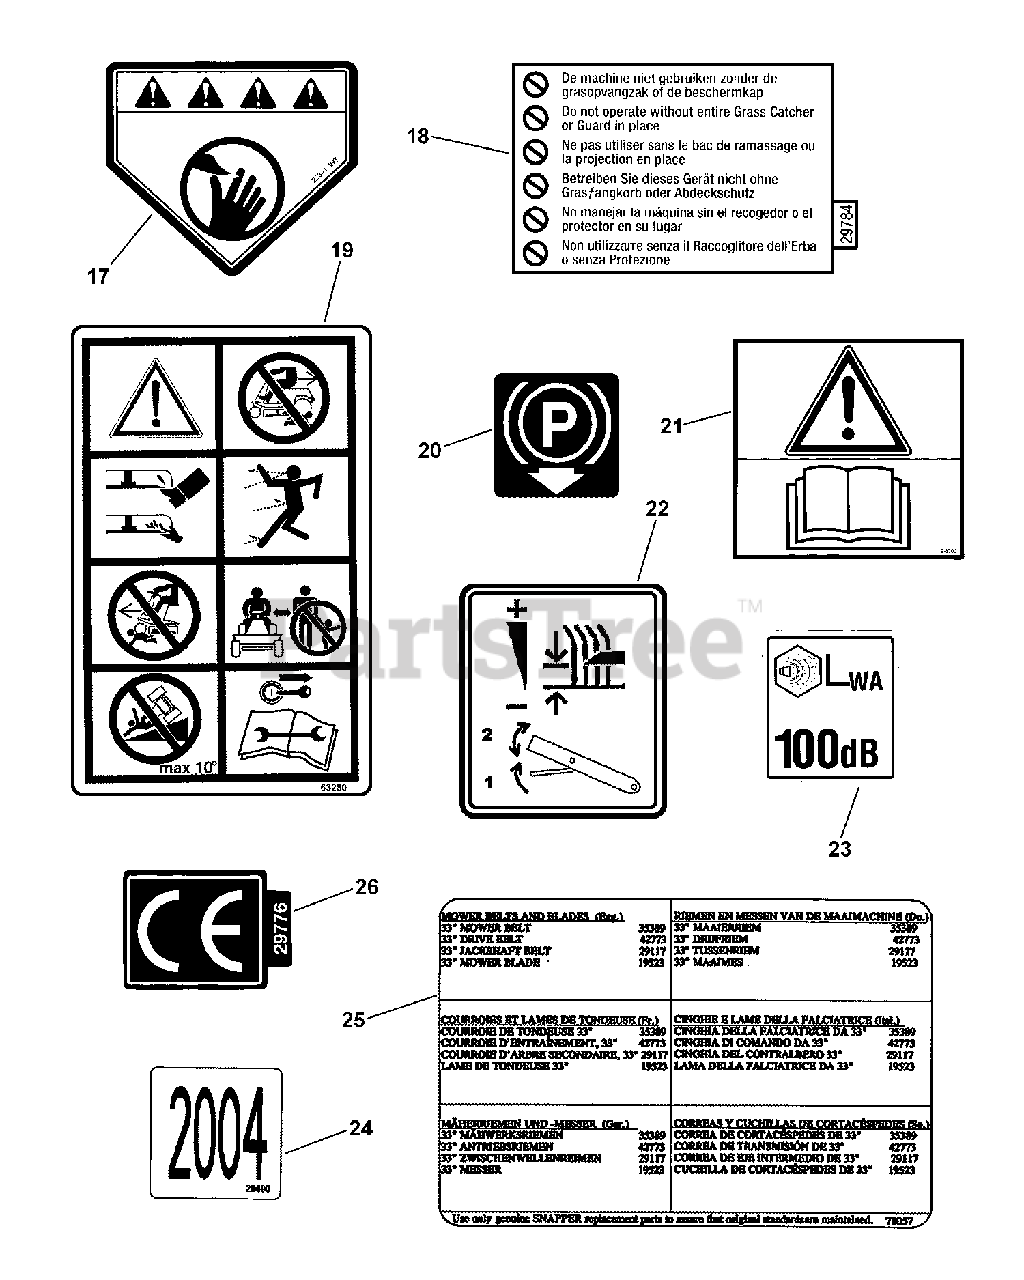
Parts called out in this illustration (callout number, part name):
17	DECAL, Warning, International Symbol
18	DECAL, Deck Chute, International Warning
19	DECAL, Safety Symbols
20	DECAL, Park Brake (Euro)
21	DECAL, Chute/Read Manual (Euro)
22	DECAL, Deck Adjust
23	DECAL, Sound 100
24	DECAL, 2004 Year of Manufacture
25	DECAL, Service Parts, HOZ Euro
26	DECAL, Euro Community (CE)
